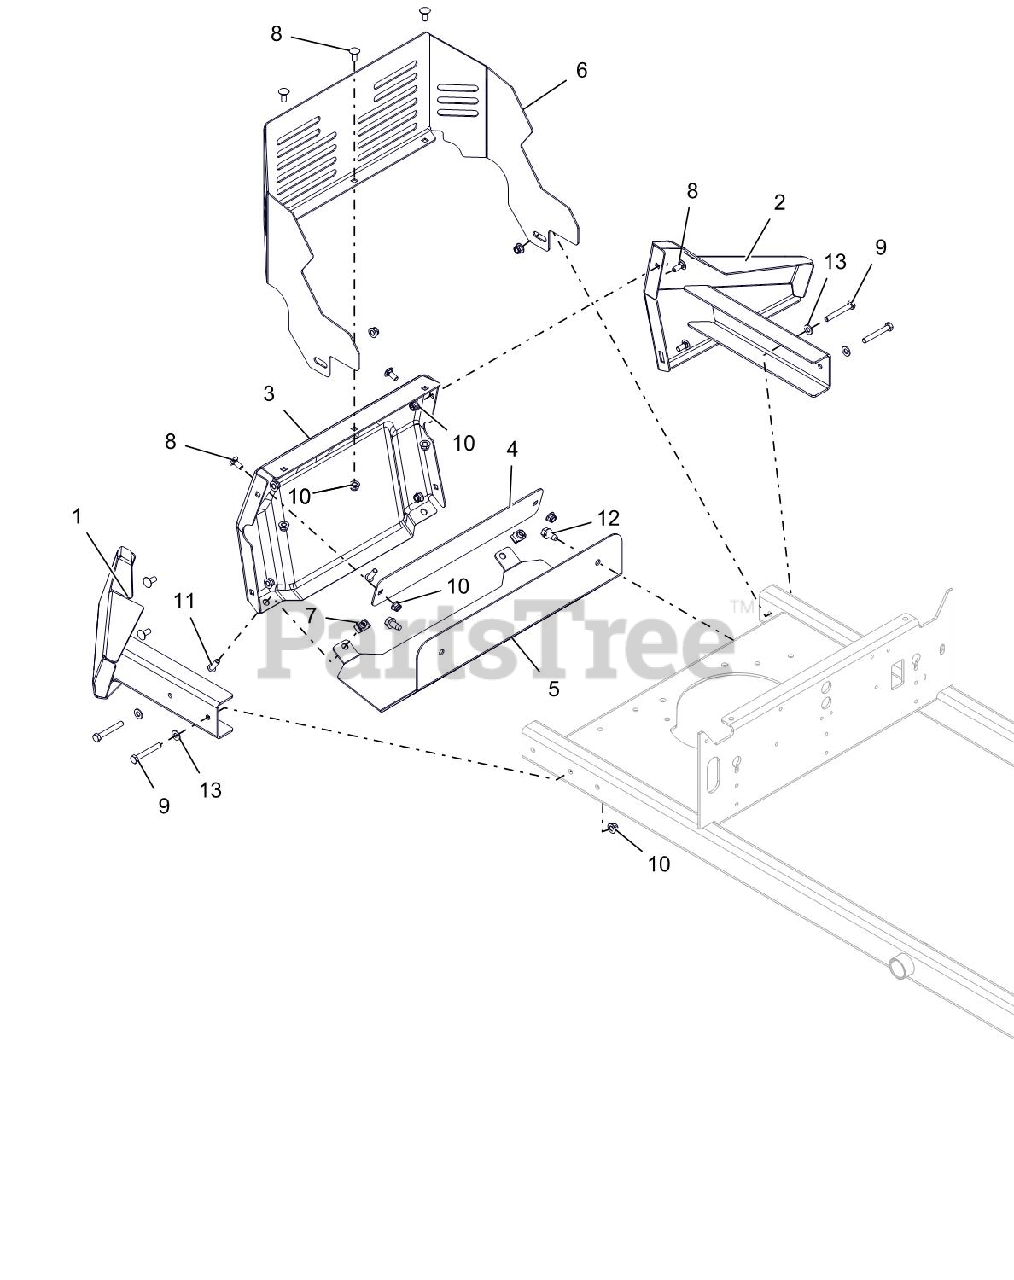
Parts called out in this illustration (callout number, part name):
1	RH RR BMPR WING W/SAFETY DECAL
2	LH RR BMPR WING W/SAFETY DECAL
3	PT200/400 REAR BUMPER - BLACK
4	BACKER PLATE - RED
5	PT100 MUFFLER GUARD -BLACK
6	GUARD, PT ENGINE
7	NUT-CLIP RETAINER 5/16-18X.56
8	@BLT-RDHDSQNK .31-18X.75 G5YZ
9	@BLT-HEX .31-18X2.25 GR5 YWZC
10	@NUT-LK-NYL-FLG .31-18 YWZC
11	SCR-SKH .31-18X1.0 BTNHD YWZC
12	@SCR-TAP .38-16X.75 HWH TR YWZ
13	@WSHR-FL-STL.344X.688X.065YWZC
